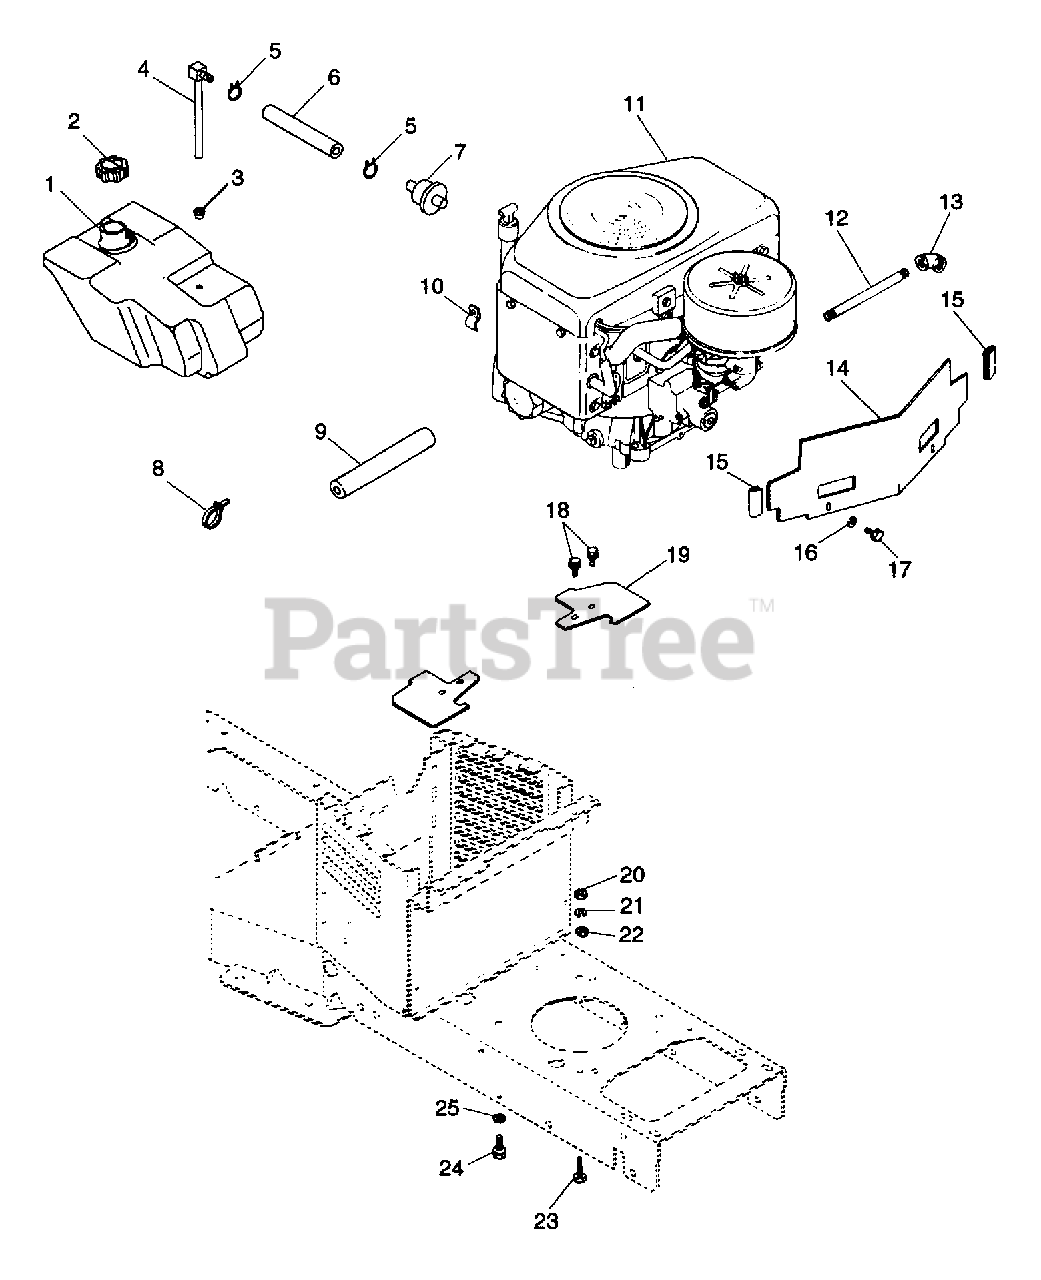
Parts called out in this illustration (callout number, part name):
1	FUEL TANK
2	FUEL CAP
3	BSHG-FLG .375 X 1.062 X .625 R
4	TANK FITTING
5	CLAMP-HOSE WIR.490/.510X.092#8
6	FUEL LINE 1/4 X 50.5"
7	FUEL FILTER
8	CABLE TIE LG 5-1/2
9	TUBING - SPONGE
10	HOSE CLAMP
11	MV16S KOHL.VER.SHFT.ENG.#56514
11	MV18S KOHLER ENGINE - PS-58532
14	ENGINE BAFFLE
15	FOAM TAPE
16	WSHR-LK .250X.077 HVY PL
17	BLT-HEX .25-20X.38 PL GR2
18	SCR-TAP 10-24X.375 CRPH 1A
19	BAFFLE-SIDE
20	NUT-HEX .312-18
21	WSHR-LK .312X.097 PL HVY
22	WSHR-FL-STL .323X.625X.062 PL
23	BLT-HEX .31-18X1.50 PL GR5
24	SCR-TAP .375-16X1.0 HWH PL TR
25	WSHR-LK-EXT .375X.050
